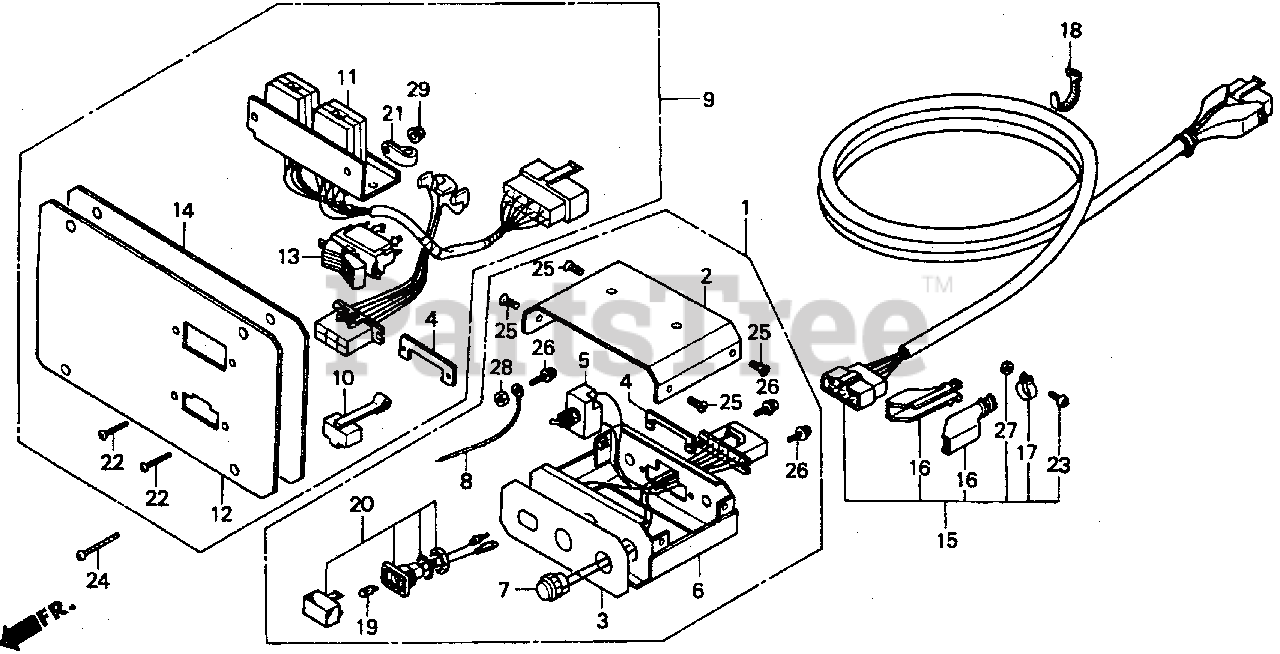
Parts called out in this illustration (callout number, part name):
1	BOX ASSY., SWITCH
2	COVER (UPPER)
3	PLATE, SWITCH & INDICATOR
4	PLATE, CONNECTOR SETTING
5	SWITCH, TOGGLE
6	PANEL, CONTROL *R8* (BRIGHT RED)
7	SWITCH, PUSH
8	WIRE, GROUND
9	CONTROL ASSY., REMOTE
11	RELAY ASSY.
12	MARK, REMOTE CONTROL
13	SWITCH ASSY.
14	PANEL, RELAY
15	CABLE, REMOTE CONTROL (10M)
16	COVER, CONNECTOR
18	BAND B1, WIRE
19	BULB, WEDGE BASE (12V/2W)
20	SOCKET ASSY., LAMP (GREEN)
21	CLIP (9MM)
22	SCREW, PAN (3X8)
23	SCREW, PAN (3X12)
24	SCREW, PAN (5X10)
25	SCREW, FLAT (4X8)
26	SCREW-WASHER (4X12)
27	NUT, HEX. (3MM)
28	NUT, HEX. (4MM)
29	NUT, FLANGE (4MM)
